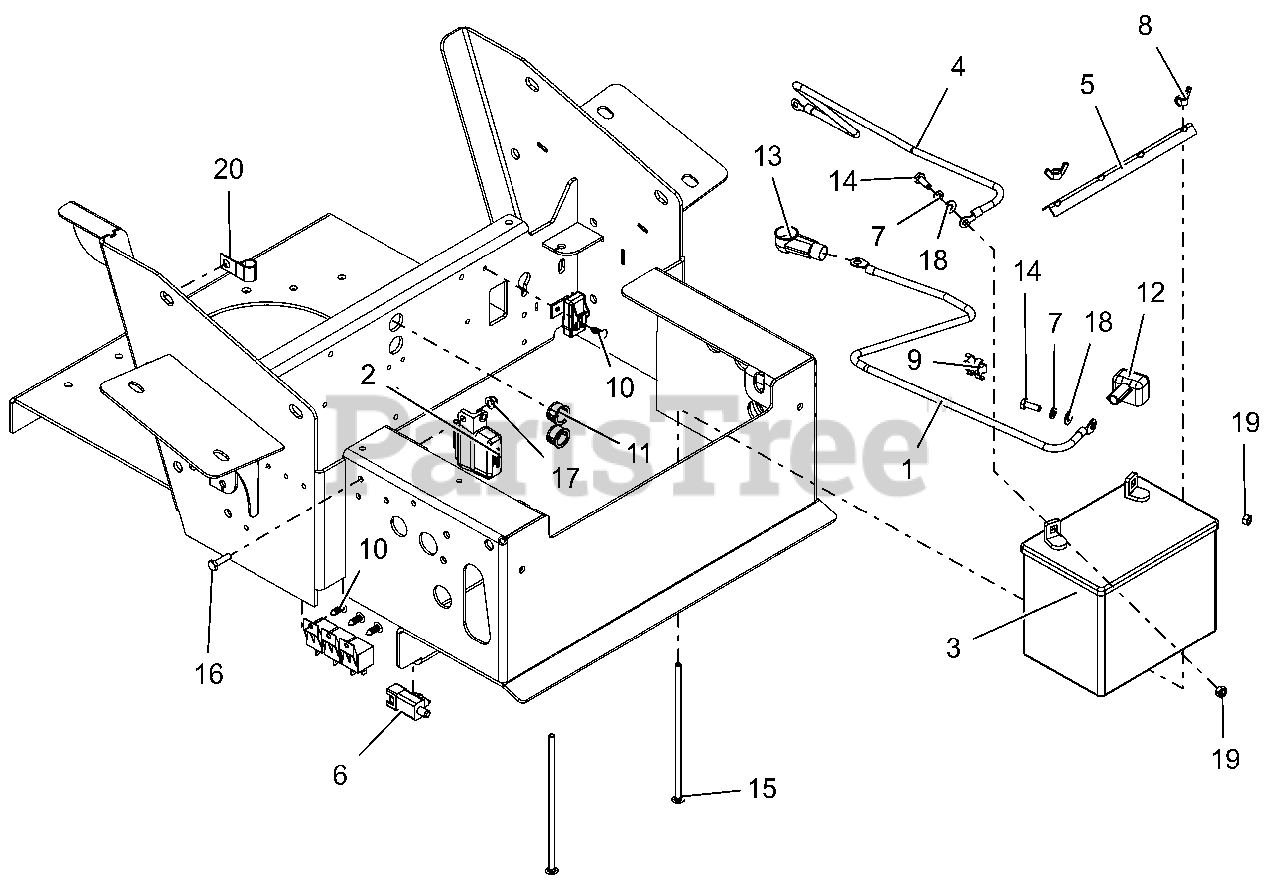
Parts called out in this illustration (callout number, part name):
1	CABLE,POS W/(2) 5/16 RING 30LG
2	HARNESS, PT100 WIRE
3	BATTERY, 300 CCA 10U1L
4	CABLE-NEGATIVE BATTERY 24.00"
5	HOLD DOWN
6	SWITCH, SNAP IN - N.O./N.O.
7	@WSHR-LK .25X.062 REG YWZC
8	NUT-LK WING .250-20 YWZC
9	CLIP,T,.31-.38,
10	RIVET, .25 NYLON PANEL
11	BUSH, PANEL SNAP .687X.875X.56
12	INSULATOR
13	BOOT, .65ID POS
14	@BLT-HEX .25-20X.75 GR5 YWZC
15	BLT-RDHDSQNK .25-20X7.50 GR2YZ
16	@BLT-HEX .25-20X1.00 GR5 YWZC
17	@NUT-LK-NYL-FLG .25-20 YWZC
18	@WSHR-FL-STL.281X.62X.065 YWZC
19	@NUT-HEX .25-20 YWZC
